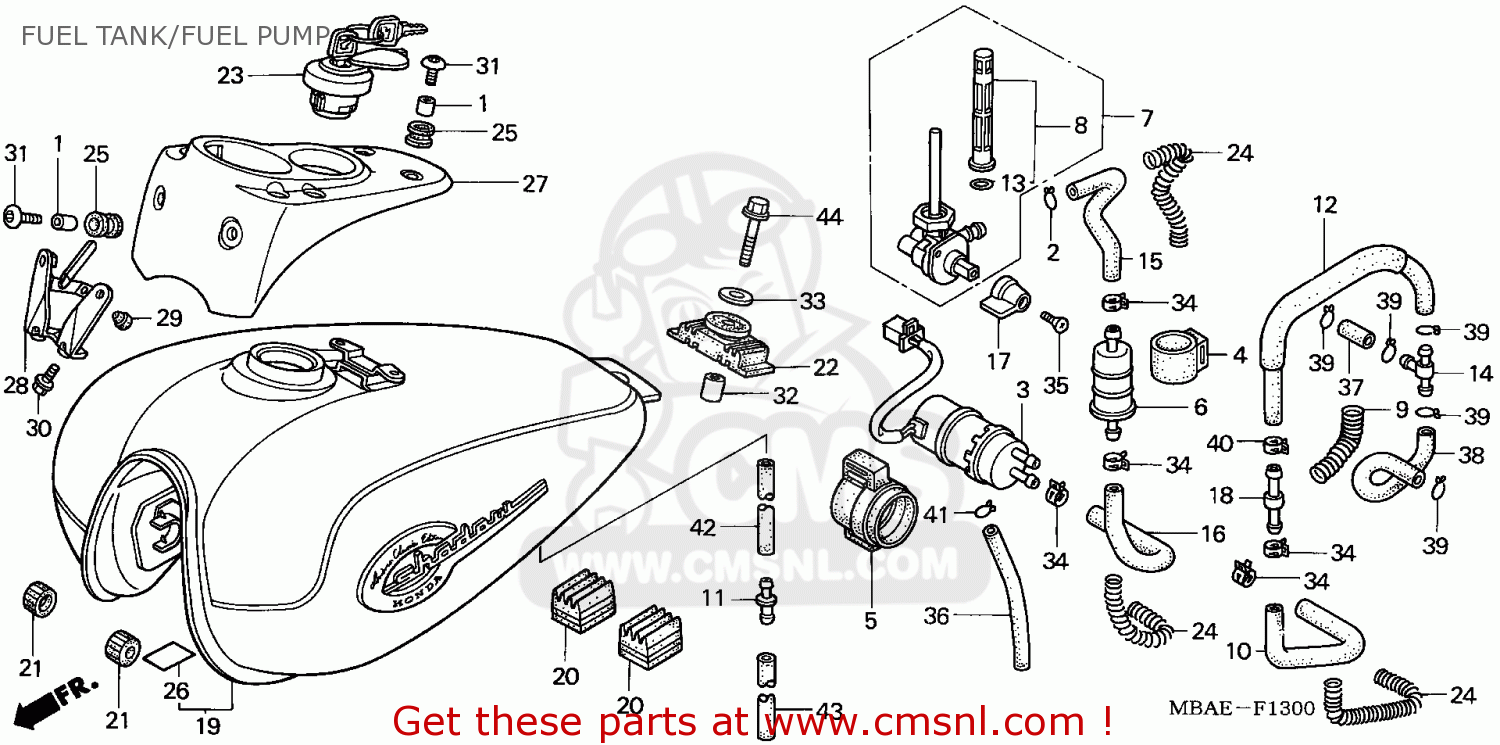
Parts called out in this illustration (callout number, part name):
1	COLLAR,ADJUST
2	CLIP,OIL DRAIN TU
3	FUEL PUMP ASSY
4	HOLDER,STRAINER
5	RUBBER FUEL PUMP
6	STRN.COMP.,FUEL
7	COCK ASSY,FUEL
8	SCREEN SET,FUEL S
9	WIREB,GUARD
10	TUBE.C,FUEL
11	JOINT,FUEL TUBE
12	TUBE D,FUEL
13	O-RING
14	JOINT,FUEL TUBE
15	TUBE.A,FUEL
16	TUBE.B,FUEL
17	LEVER,FUEL COCK
18	JOINT,FUEL TUBE
19	SET ILLUS*TYPE12*
20	CUSH.FUEL TANK
21	CUSHION,FUEL TANK
22	CUSHION,FUEL TANK
23	CAP COMP,FUEL FIL
24	WIRE,GUARD
25	RUBBER,PKG.PROTR. (NAS)
26	TAPE A
27	COVER,METER
28	STAY,FR.METER
29	RUB.,NO.BRKT.CUSH
30	BOLT,FLANGE
31	SCREW,PAN,6X14
32	COLLAR RR CUSHION
33	WASHER,8.5X28
34	CLAMP. CNSTR HOSE
35	SCREW,PAN 5X12
36	TUBE,FUEL,4.5X100
37	TUBE,FUEL,7.3X35
38	TUBE,FUEL,7.5X200
39	CLIP B12,TUBE
40	CLAMP D 12.0 TUBE
41	CLIP,TUBE 5.0MM
42	TUBE 45X520
43	TUBE,7.3X500
44	BOLT,FLANGE,8X35
